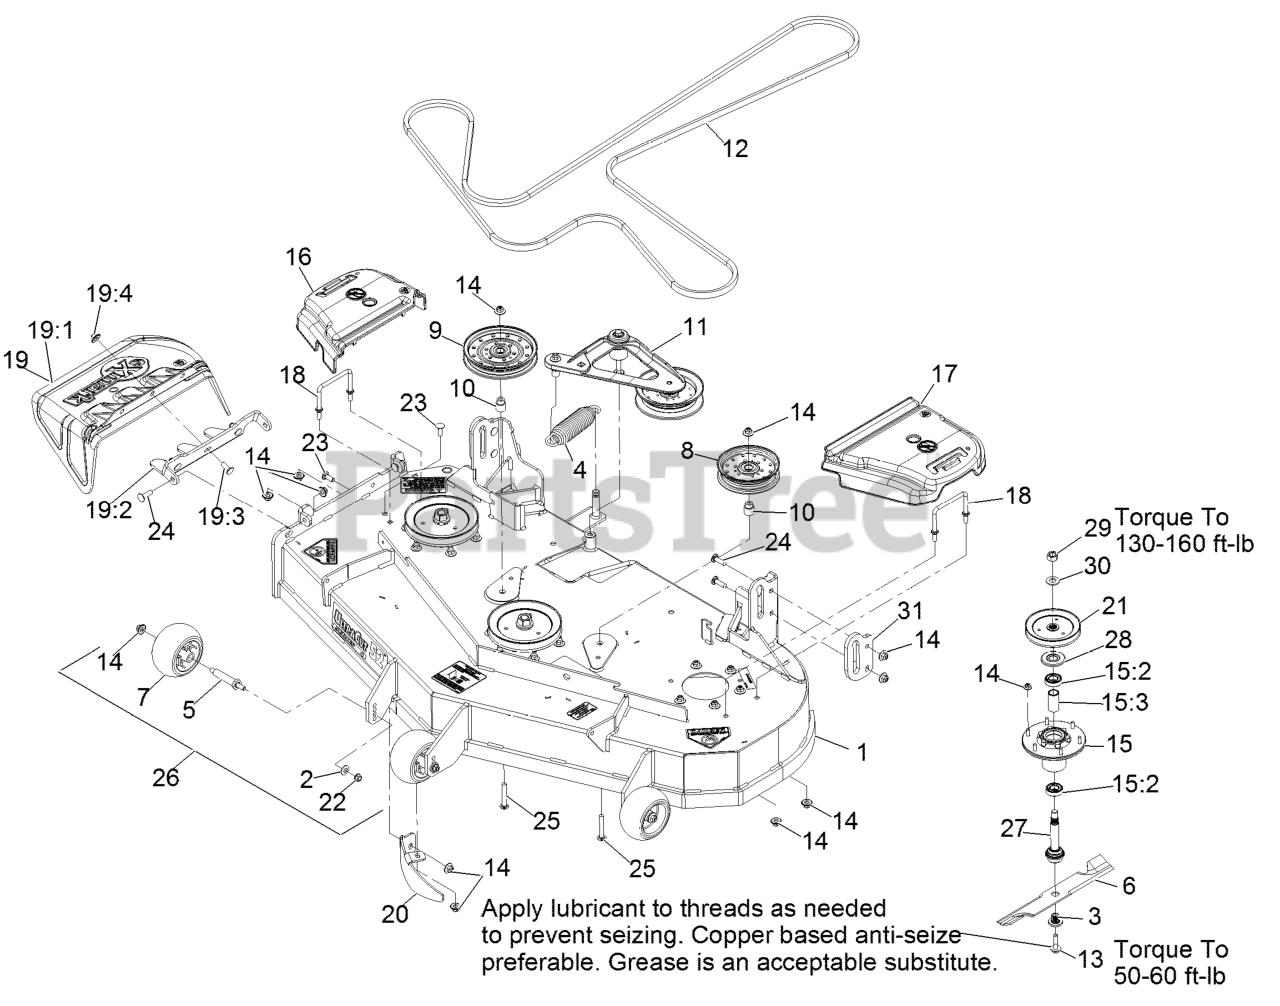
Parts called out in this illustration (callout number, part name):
1	ASM, DECK W/DECALS 524
2	WASHER-BELLEVILLE
3	BUSHING,SPLINED
4	SPRING-EXTENSION
7	ROLLER-SCALP, ANTI
10	BUSHING-IDLER
11	DECK IDLER ASM
12	BELT,V-B X 186.00"
13	SCREW,SEMS 1/2-20 X 2.19
14	Nut-Nyloc 3/8-16 Flg
15	ASM-CUTTER HSG WITH BEARINGS
15:2	BEARING-BALL
15:3	SPACER-BEARING
16	COVER-BELT, RH
17	COVER-BELT, LH
18	WIREFORM-COVER
19	ASM,DISCHARGE CHUTE
19:1	CHUTE,DISCHARGE
19:2	BRACKET,DISCHARGE CHUTE
19:3	SCREW-CARR
19:4	Nut-Nyloc 3/8-16 Flg
20	BAFFLE-DOGLEG, LZE-PNS-52
21	SHEAVE,BLADE DRIVE 6.50
22	NUT-HHF, WHIZ
23	SCREW-CARR
24	Bolt-Carriage 3/8-16 X 1 1/4
25	SCREW-CARR
27	ASM-SPINDLE AND SEAL
28	GUARD,BEARING TOP .989
29	NUT-HEX
31	PLATE-REINF, PUSH TOWER
